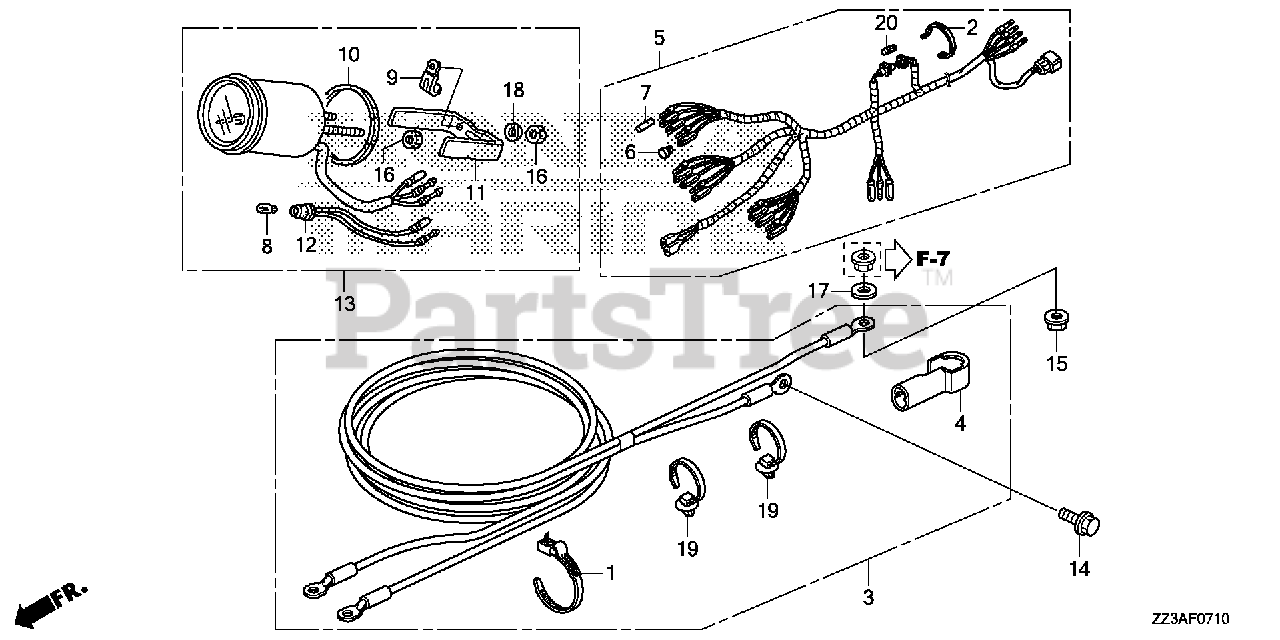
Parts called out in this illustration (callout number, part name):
1	BAND, WIRE (165MM) (BLACK)
3	CABLE ASSY., STARTER
4	COVER, STARTER TERMINAL
14	BOLT, FLANGE (8X18)
15	NUT-WASHER (8MM)
17	WASHER, PLAIN (8MM)
19	CLIP, HARNESS BAND (145MM) (BLACK)
